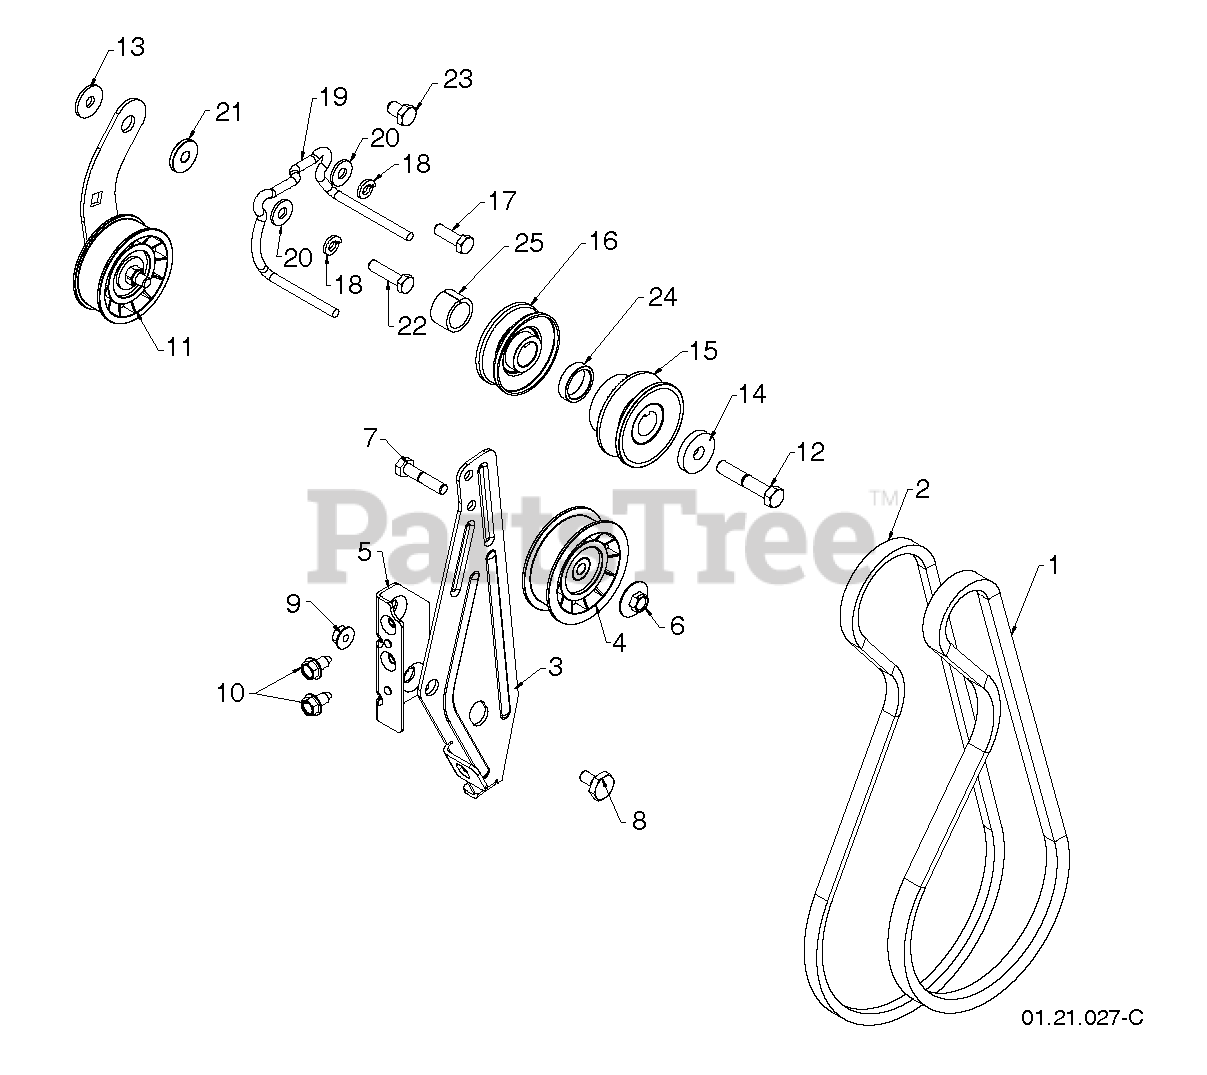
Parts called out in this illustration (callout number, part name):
1	V-BELT.IMPELLER
2	V-BELT.TRACTION
3	ARM.IDLER BRAKE.CLEAR.ZINC
4	PULLEY.W/SPACER.2.75
5	BRACKET.IDLER.PIVOT.ZINC
6	NUT.FLANGE.HEX.5/16X18.BLACK
7	HEX BOLT
8	BOLT.SHOULDER.1/2X12
9	NUT.LOCK.5/16-18
10	BOLT.5/16HEX.WHS.HD
11	ARM.ASM.TRACTION.IDLER.
12	BOLT.BLADE
13	STEEL WASHER
14	WASHER.400X1.25X5.
15	PULLEY IMPELLER.ASM.2.60_.75 B
16	PULLEY,ENGINE TRACTION DRIVE
18	LOCKWASHER
19	GUIDE.BELT.CHAIN.LS.SNOW
20	WASHER.20X8.5
21	BUSHING.BRAKE.ARM
22	CAPSCREW.HEXHD.5/16X1.25.
23	SCREW.3/8-16 X .750 (2 2)
24	SPACER.ENGINE.PULLEY
25	SPACER AXLE
